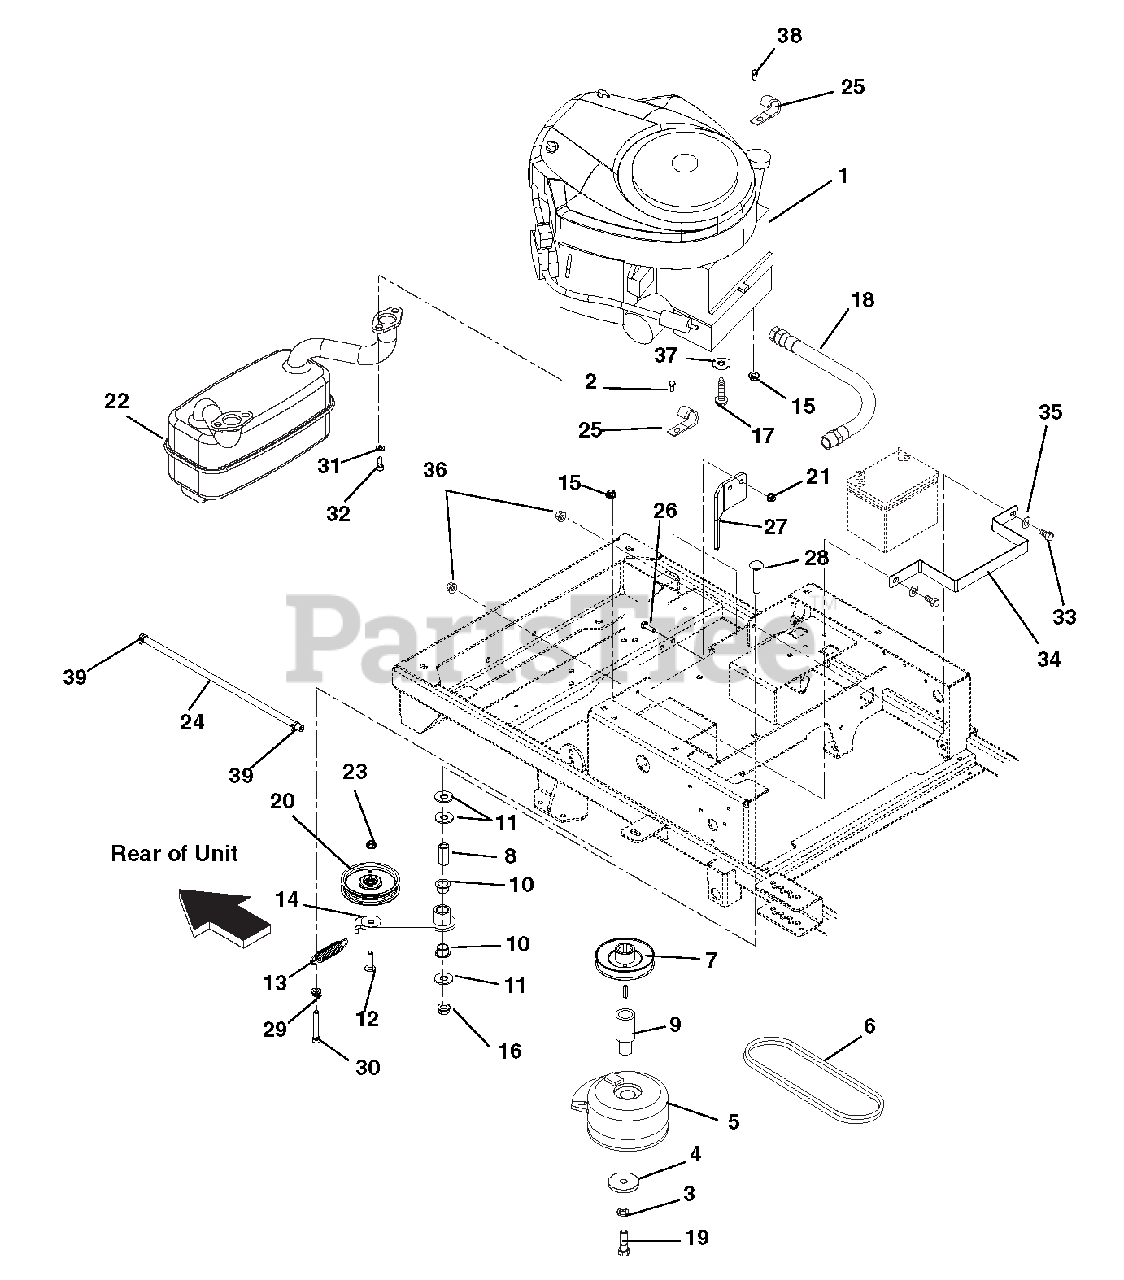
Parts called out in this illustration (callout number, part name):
1	FR651-22 KAWASAKI TWIN ENGINE
2	@SCR-TAP .25-20X.37 HWH YWZ TR
3	@WSHR-LK .44X.109 REG YWZC
4	WSHR-FL-STL .469X2.00X.25 YWZC
5	CLUTCH, MS
6	V-BELT, HA-WRAPPED
7	PLY-V 4.5X1.5 AB SECTION W/KEY
8	BSHG-SLV .500X.750X1.560
9	EXT-CRANKSHAFT LOWER
10	BSHG-FLG 0.75X0.875X.625X1.125
11	@WSHR-FL-STL.563X1.38X.109YWZC
12	@BLT-RDHDSQNK .38-16X1.50 G5YZ
13	SG-TENS .105X.812X3.88 WLD 15
14	WMT, GROUND DRIVE IDLER ARM
15	@NUT-LK-NYL-FLG .38-16 YWZC
16	@NUT-LK-TOP-FLG .50-13 YWZC
17	BLT-HEX.38-16X1.25FTHG5 EP30YZ
18	OIL DRAIN HOSE
19	BLT-HEX .44-20X4.50 GR8 YWZC
20	ASM, 4" IDLER (.75 WIDE)
21	@NUT-LK-NYL-FLG .31-18 YWZC
22	MUFFLER, TWIN
23	@NUT-LK-TOP-FLG .38-16 YWZC
24	HOSE, .25 LOW-PERM BULK GAS
25	J-CLAMP
26	@BLT-HEX .31-18X1.00 GR5 YWZC
27	CLUTCH STOP
28	@BLT-RDHDSQNK .50-13X2.50 G5YZ
29	@NUT-SPNLK-FLG .375-16 YWZC
30	@BLT-HEX .38-16X2.50 GR5 YWZC
31	@WSHR-LK .31X.078 REG YWZC
32	SCR-CAP .31-18X.75 S/HD
33	@BLT-HEX .25-20X.75 GR5 YWZC
34	BRKT, BATTERY HOLD DOWN
35	@WSHR-FL-STL.281X.62X.065 YWZC
36	NUT-KEPS .250-20
37	@WSHR-FL-STL.406X.812X.065 YWZ
38	@BLT-HEX .38-16X.75 GR5 YWZC
39	CLAMP, FUEL LINE
